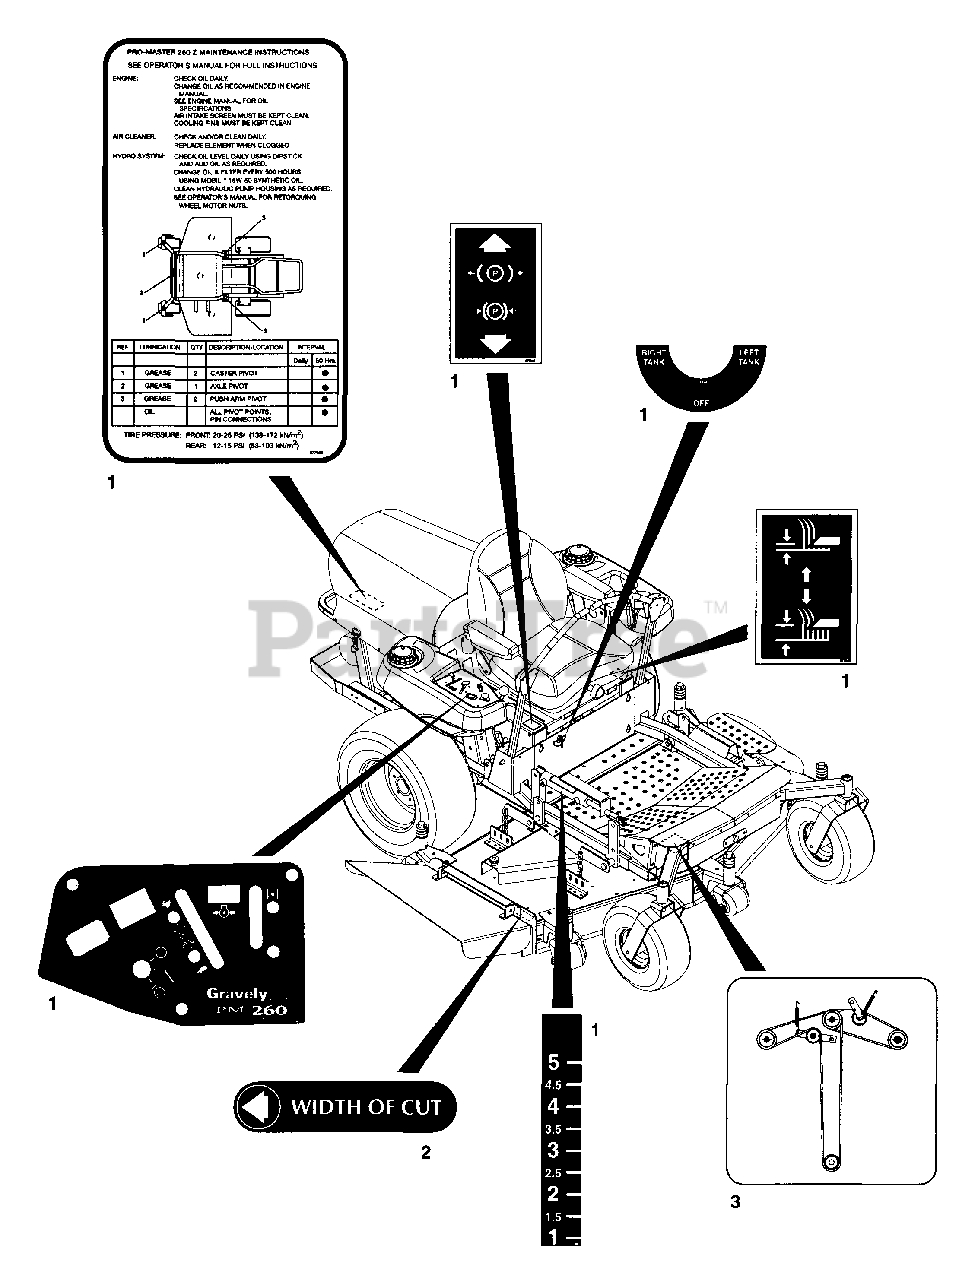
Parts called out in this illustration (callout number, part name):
1	Decal Set PM260Z
2	Decal Set Mower Decks
3	Decal, GRAVELY Belt Diagram
4	Decal Set GRAVELY Logo
